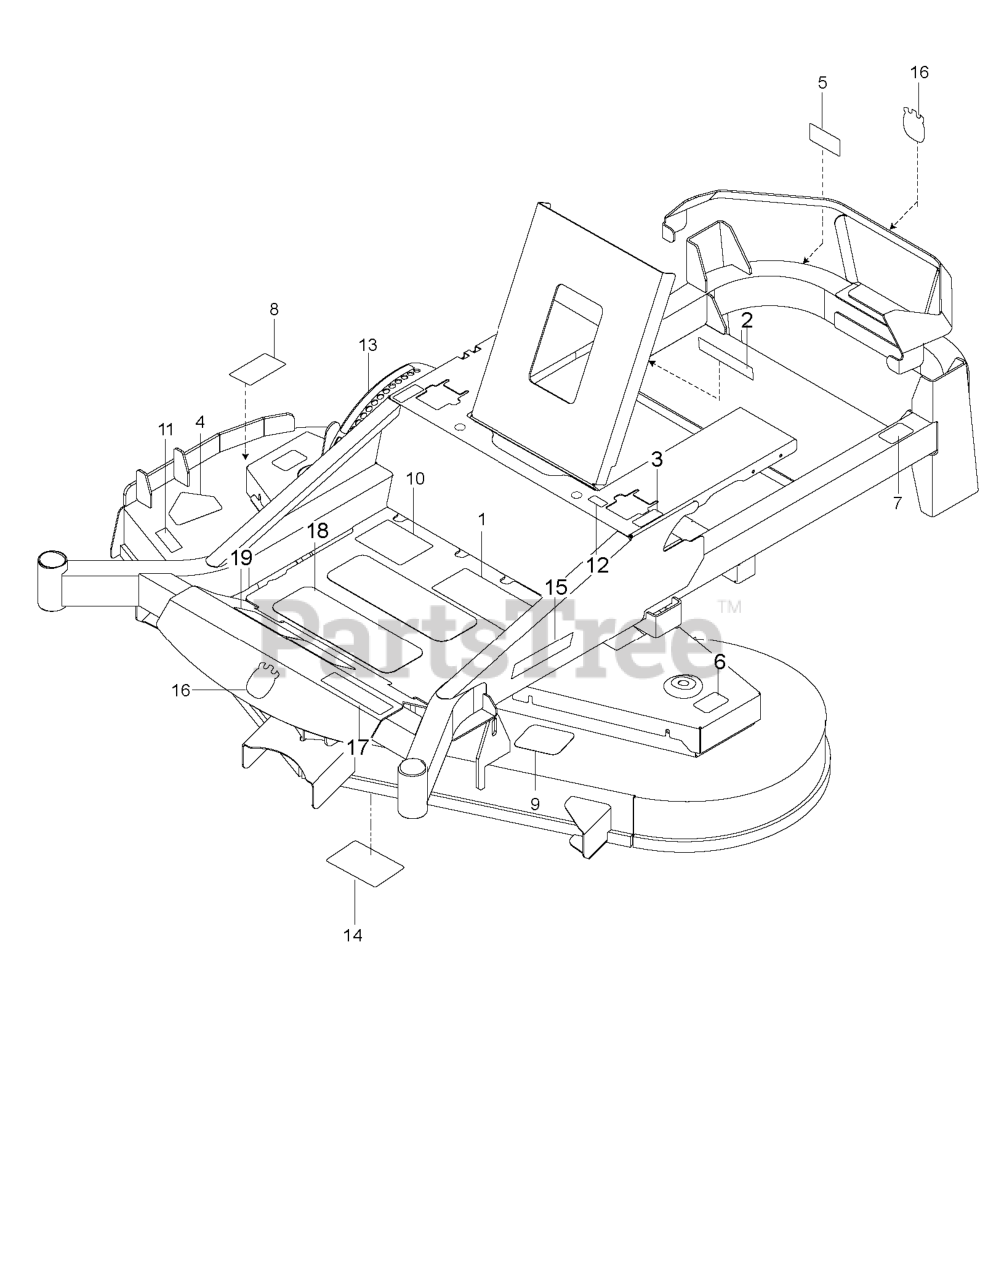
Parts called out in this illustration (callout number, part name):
1	DECAL, WARNING
2	EURO DECAL-BATTERY WARNIN6
3	DECAL, MOTION CONTROL
4	DECAL, CPSC
5	DECAL, BELT DRIVE
6	DECAL, NO STEP
7	DECAL, PROP. 65
8	DECAL, CAUTION
9	DECAL, BELT ROUTING
10	DECAL, WARNING
11	DECAL, EURO SEVERING
12	DECAL, F.S.T.
13	DECAL, HEIGHT ADJUST
14	DECAL, SERVICE
15	RP.DECAL.BADGE.170MM.TEXTLOGO
16	DECAL.AUGER.HUSQ.CROWN.SNOW
17	DECAL, MZ6128
18	ANTI-SKID PAD
